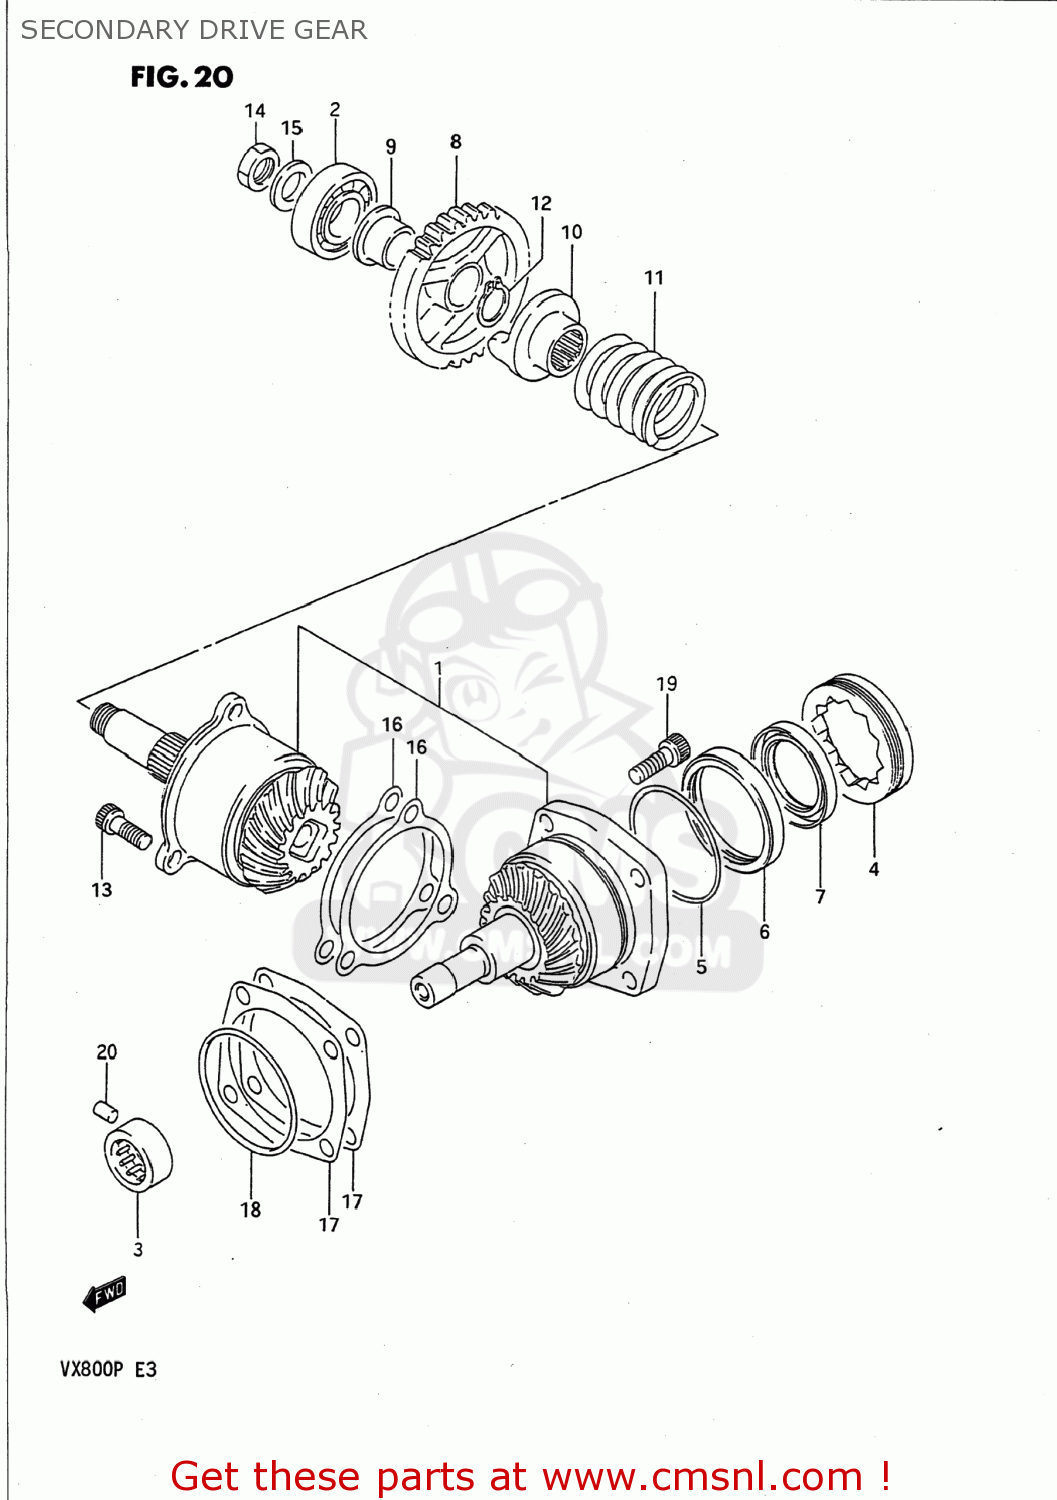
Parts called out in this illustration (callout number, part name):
1	GEAR & HOUSING SET,SECONDARY
2	BEARING(20X52X15)
3	BEARING(20X34X16)
4	STOPPER,SEC DRIVEN BEARING
5	O RING(D:1.2,ID:59.6)
6	HOUSING,OIL SEAL
7	SEAL,OIL(38X54X8.5)
8	GEAR,REDUCTION DRIVEN(NT:30)
9	BUSH,REDUCTION DRIVEN GEAR
10	DOG,OUTPUT CAM
11	SPRING
12	CIRCLIP
13	BOLT
14	NUT
15	WASHER(16X29X4)
16	SHIM,SECONDARY DRIVE
17	SHIM,SECONDARY DRIVEN HOUSING
18	O RING(D:2.1,ID:66.2)
19	BOLT
20	PIN
